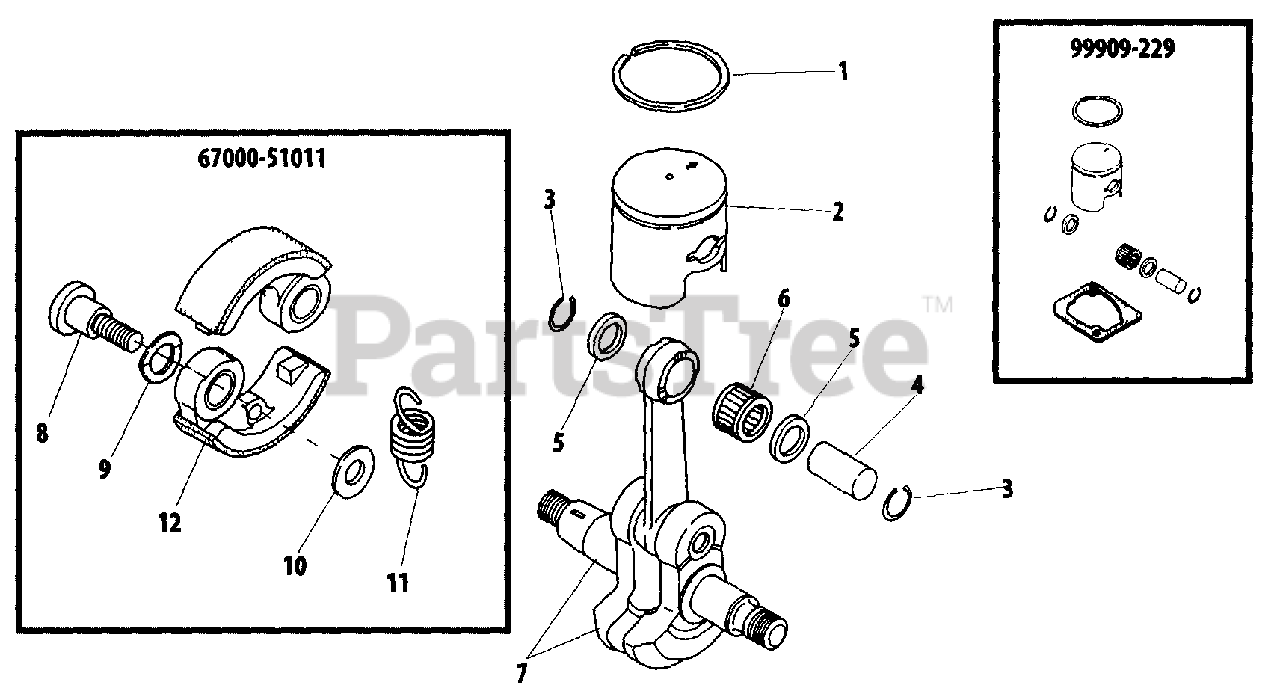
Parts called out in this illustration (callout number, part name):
1	RING, PISTON
2	PISTON
3	RING, SNAP
4	PIN, PISTON
5	WASHER, THRUST
6	BEARING, NEEDLE
7	CRANKSHAFT
8	BOLT
9	WASHER, SPRING
10	WASHER 6 MM
11	SPRING, CLUTCH
12	SHOE, CLUTCH
67000-51011	SHOE ASSY, CLUTCH
99909-229	PISTON KIT
